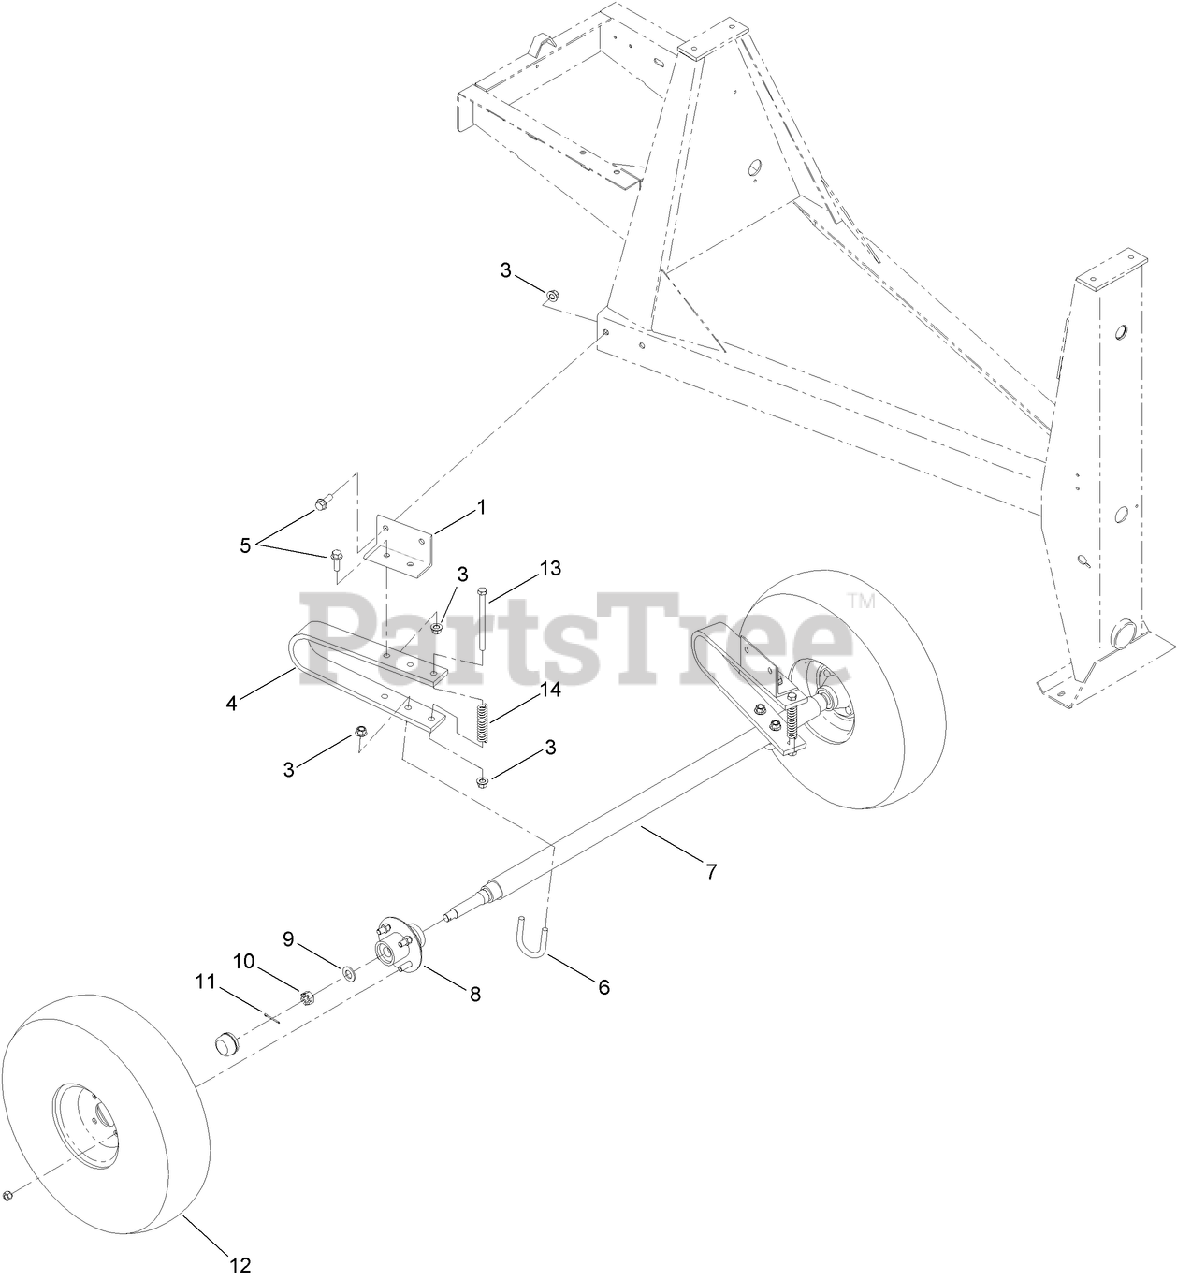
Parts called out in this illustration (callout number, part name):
1	BRACKET-AXLE, SPRING
3	NUT-LOCK
4	SPRING-LEAF
5	SCREW-HHF
6	BOLT-U
7	AXLE-SPRING
8	HUB ASM
9	WASHER-FLAT
11	PIN-COTTER
12	TIRE AND RIM ASM
13	SCREW-HH
14	SPRING-COIL
